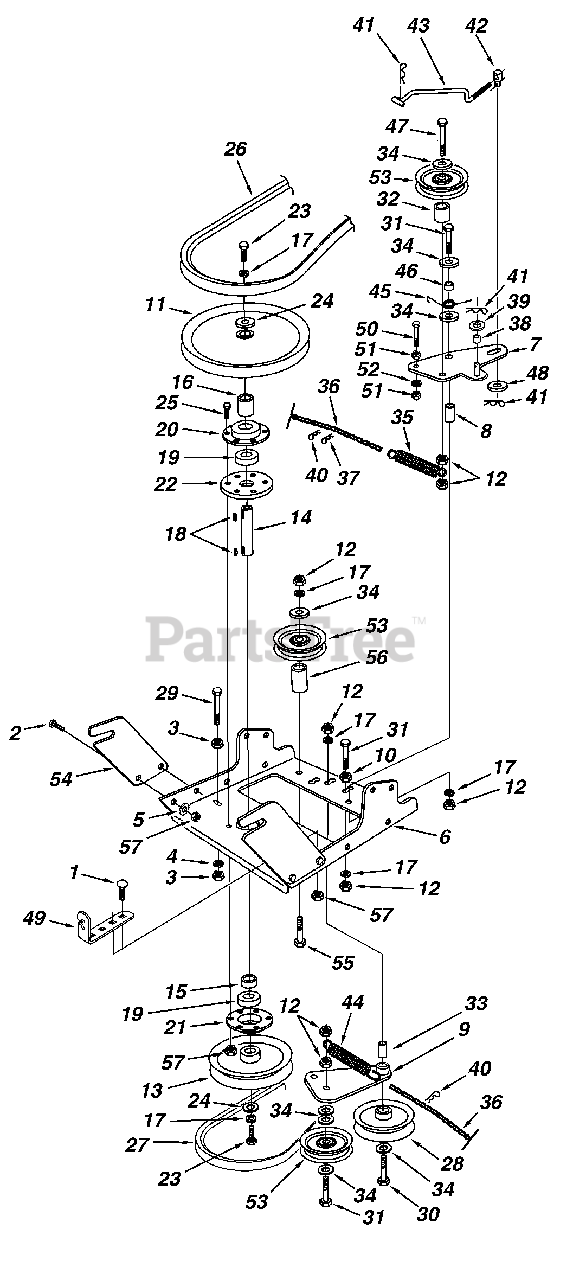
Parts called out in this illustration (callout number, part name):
1	Carriage Bolt, 5/16-18 x 3/4"
2	Hex Bolt, 5/16-18 x 3/4"
3	Hex Nut, 5/16-18
4	Lock Washer, 5/16"
5	Washer, 5/16" Std. Wrt.
6	Frame, Clutch and Pulley
7	Idler Arm Assembly
8	Spacer, Pivot
9	Idler Bracket Assembly
10	Hex Nut, 3/8-16
11	Pulley, V Type 9"
12	Nut, Hex Lock, 3/8-16
13	Pulley, V Type 5-1/2"
17	Lock Washer, 3/8"
19	Bearing, Ball
20	Housing, Bearing
21	Housing, Open Bearing
22	Spacer, Spindle
23	Hex Bolt, 3/8-24 x 1"
25	Hex Bolt, 5/16-18 x 1"
26	Belt, V Type Drive
27	Belt, V Type Auger
28	Pulley, V Type 4"
29	Hex Bolt, 5/16-18 x 3-1/2"
30	Hex Bolt, 3/8-16 x 2-1/2"
31	Hex Bolt, 3/8-16 x 2"
33	Spacer, Pivot
34	Washer, 3/8"
37	Pin, Hair Cotter, 3/32"
39	Washer, 1/4"
40	Pin, Hair Cotter #4
41	Pin, Hair Cotter 5/64"
43	Rod, Engagement
45	Spring, Torsion
47	Hex Bolt, 3/8-16 x 2-3/4" Lg.
48	Washer, Flat 3/8"
49	Cable Bracket
50	Hex Bolt, 1/4-20 x 2-1/2"
51	Hex Nut, 1/4-20
52	Lock Washer, 1/4"
53	Pulley, Flat 3-5/8"
54	Rear Pulley Frame Bracket
55	Hex Bolt, 3/8-16 x 3-1/4"
57	Hex Nut, 5/16-18 Nylock
